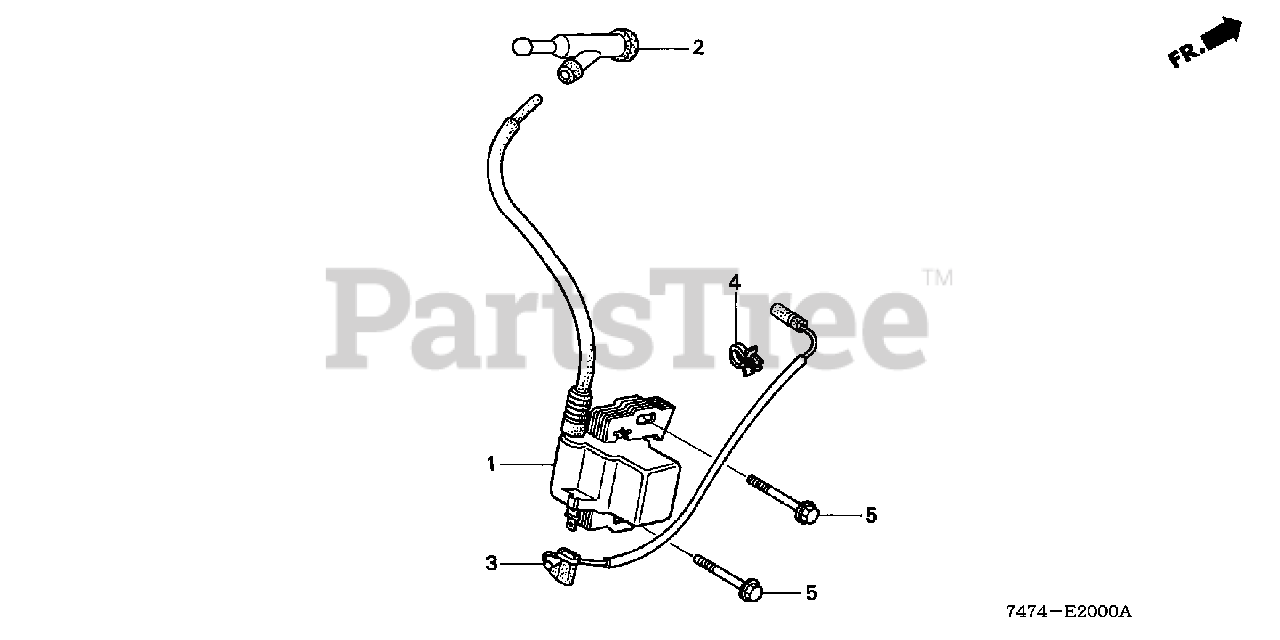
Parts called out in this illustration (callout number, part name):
1	COIL ASSY., IGNITION
2	CAP ASSY., NOISE SUPPRESSOR
3	WIRE, STOP SWITCH
4	HOLDER, STOP SWITCH WIRE
5	BOLT, FLANGE (6X25)
